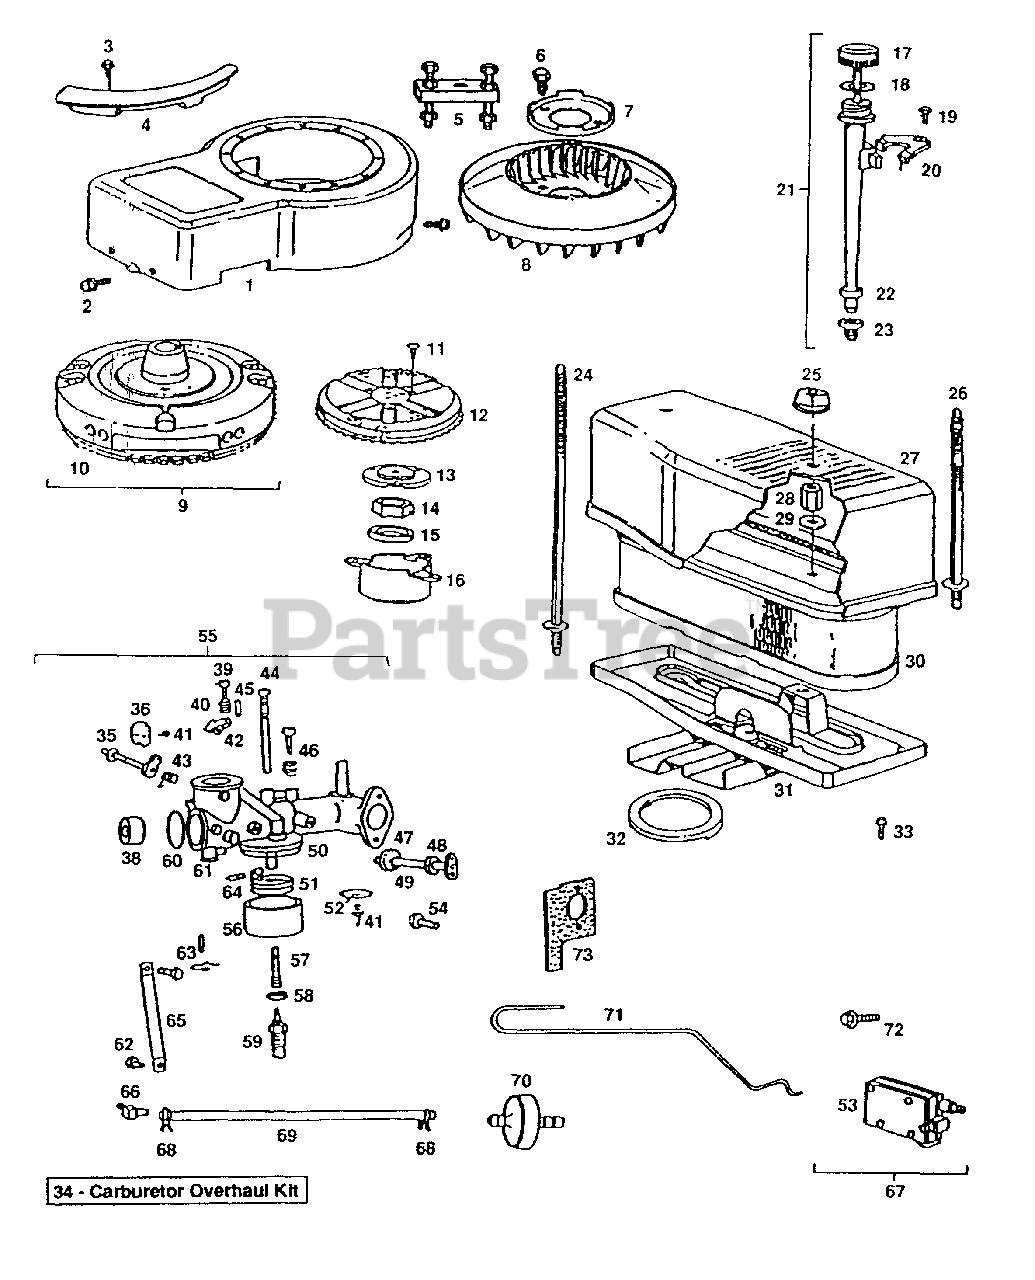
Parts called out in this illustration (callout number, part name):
1	Housing, Blower
2	Screw, Blower Housing Mounting Sem
3	Screw, Hex Hd.
4	Guard, Flywheel
5	Puller, Flywheel
6	Screw, Sem 3/4" Long
7	Retainer, Fan
8	Fan Flywheel
9	Flywheel and Ring Gear Assy - Magneto
10	Gear, Ring
11	Screw, Sem
12	Screen, Flush Rotating
14	Nut Hex
15	Washer, Spring
16	Cup, Screen Mounting
17	Cap and Dipstick, Oil Filter
18	Seal, Oil Filler Cap
19	Screw, Clamp Mounting
20	Clamp, Oil Filler Tube
21	Fill Group, Oil
22	Tube, Oil Filler
23	Seal, Filler Tube
24	Stud, Air Cleaner
25	Knob, Air Cleaner
26	Stud, Air Cleaner
27	Cover Air Cleaner
28	Nut, Air Cleaner Mtg.
29	Washer, Air Cleaner
30	Cartridge, Air Cleaner
31	Body, Air Cleaner
32	Gasket, Air Cleaner
33	Screw, Air Cleaner Sem
34	Carburetor Overhaul Lit
35	Washer, Choke Shaft
36	Valve, Choke
37	Shaft and Lever, Choke
38	Venturi, Carburetor
39	Screw, Machine Fit Hd. 8-32 x 5/8"
40	Spring, Throttle Adjustment
41	Screw, Throttle and Choke Valve Mtg. Sem
42	Stop, Throttle
43	Spring, Choke Return
44	Nozzle, Carburetor
45	Pin, Throttle Stop
46	Valve Assembly, Carburetor Idle
47	Washer, Throttle Shaft Seal (Foam)
48	Seal, Throttle Shaft
49	Shaft and Lever, Throttle
50	Gasket, Flat Bowl
51	Float, Carburetor
52	Valve, Throttle
53	Pump, Impulse
54	Screw, Carburetor
55	Carburetor Assembly
56	Bowl, Float
57	Screw, Nozzle
58	Washer, Float Bowl
59	Valve, Needle
60	Plug, Welch
61	Body Assembly, Carburetor
62	Screw, Carburetor
63	Valve, Fuel Inlet
64	Pin, Float Hinge
65	Bracket, Carburetor
66	Connector, Fuel Pipe
67	Repair Kit, Pump
68	Clamp, Fuel Pipe
69	Fuel Line (11" Long)
70	Filter, Fuel (In Fuel Line)
71	Link, Choke
72	Screw, Sem
73	Gasket, Carburetor Mounting
